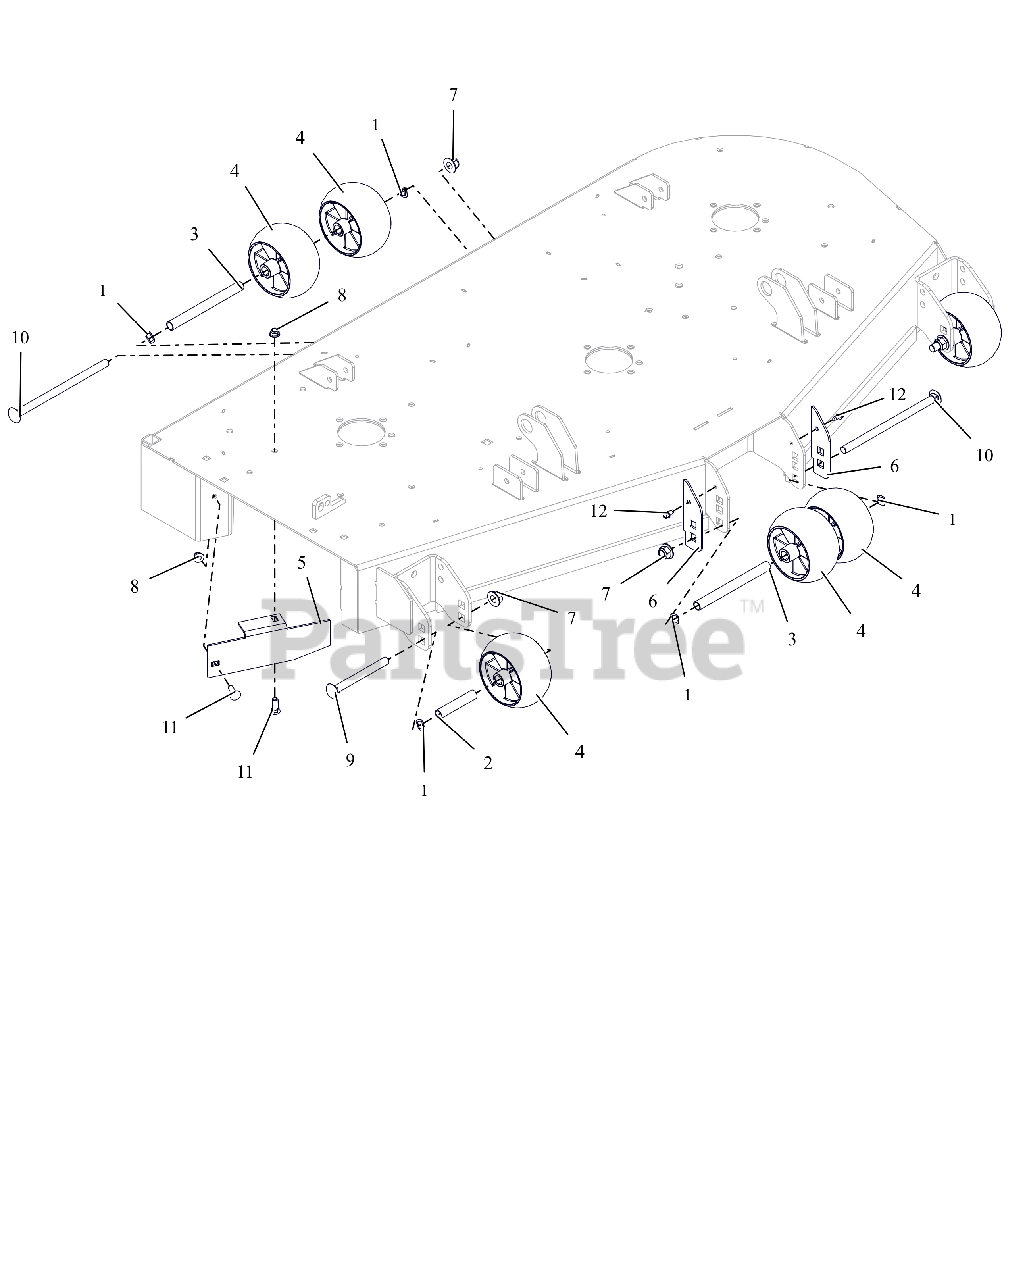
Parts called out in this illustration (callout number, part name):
1	WAVE WASHER .531X.781X.125FH
2	SPACER, .510X.625X3.35
3	SPACER, .510X.625X6.50
4	ANTI-SCALP WHEEL - 5X3 CTR
5	BAFFLE, DISCHARGE, 52"
6	PLATE, ANTI SCALP WHEEL EXT.CE
7	NUT,NYL-FLG .50-13 GF ZCC
8	NUT,LK-NYL-FLG .31-18 G5ZC120
9	BLT, RHSN .50-13X5.00 G5 ZCC
10	BLT, RHSN .50-13X8.50 G5 ZCC
11	BLT,RHSN .31-18X1.00 G5 ZCC
12	SCR-TAP .25-20X.50 HWH ZCC
